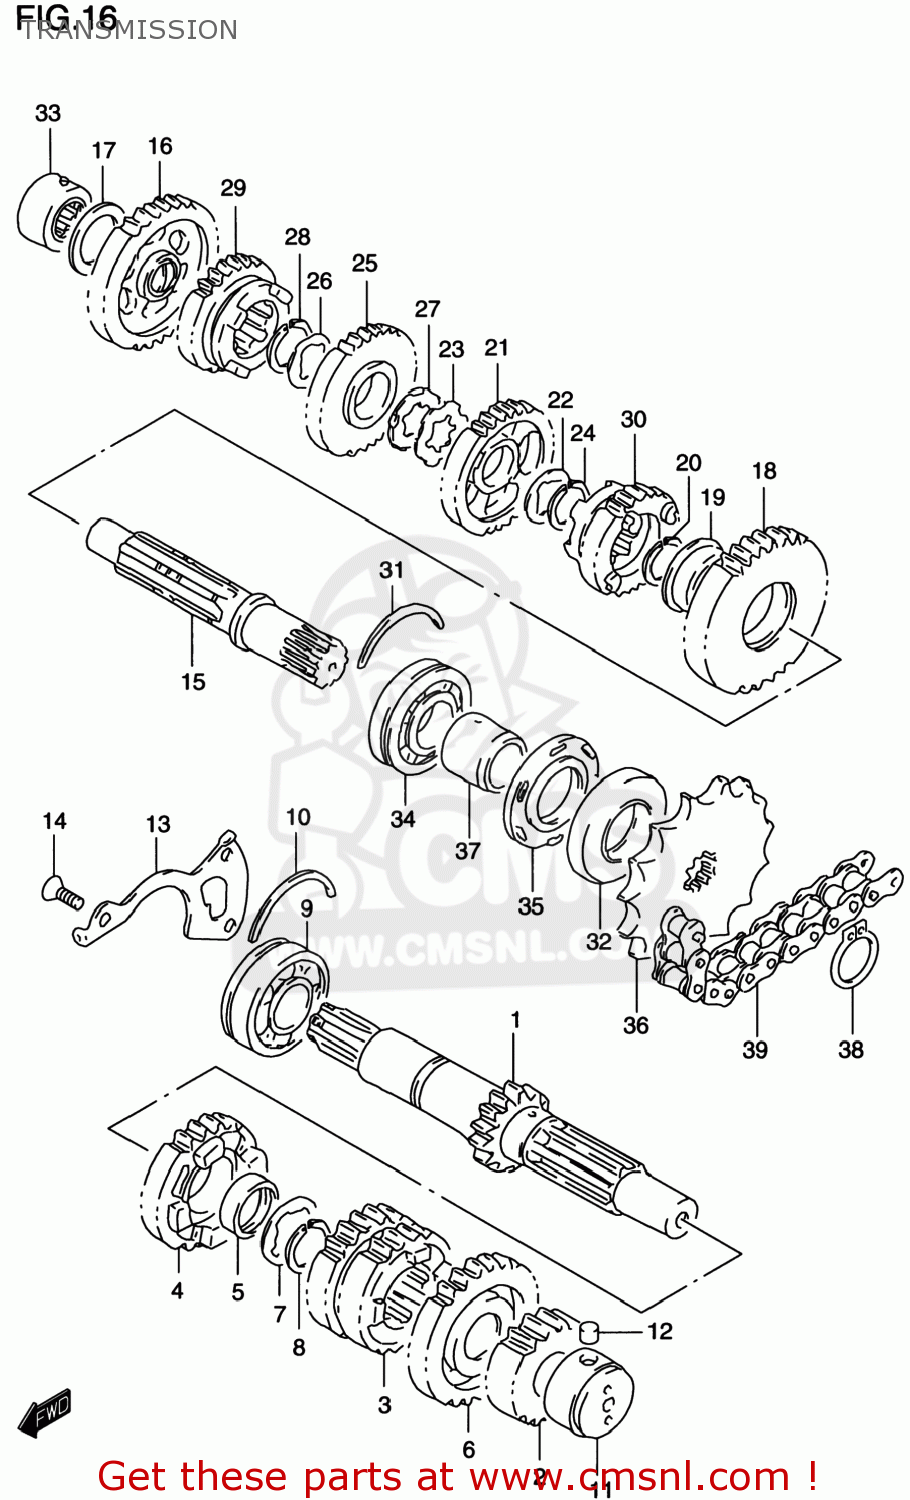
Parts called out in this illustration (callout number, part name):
1	SHAFT,COUNTER
2	GEAR,2ND DRIVE(NT:18)
3	GEAR,THIRD DRIVE
4	GEAR,FIFTH DRIVE (NT:26)
5	BUSHING 25X29X10
6	GEAR,6TH DRIVE
7	WASHER
8	CIRCLIP
9	BEARING(25X62X17)
10	C RING
11	BEARING(20X34X20)
12	PIN
13	PLATE,COUNTERSHAFT BEARING
14	SCREW ,6X16
15	SHAFT,DRIVE
16	GEAR,1ST DRIVEN
17	WASHER
18	GEAR,SECOND DRIVEN
19	BUSHING
20	CIRCLIP
21	GEAR,3RD DRIVEN
22	WASHER,LOCK
23	WASHER,LOCK
24	CIRCLIP
25	GEAR,4TH DRIVEN
26	WASHER,LOCK
27	WASHER
28	CIRCLIP
29	GEAR,5TH DRIVEN(NT:25)
30	GEAR,SIXTH DRIVEN
31	C RING
32	SEAL,OIL(32X62X7)
33	BEARING(20X34X17)
34	BEARING(25X62X17)
35	SEAL,OIL(32X62X5.5)
36	SPROCKET,ENGINE(16T)
37	SPACER,ENGINE SPROCKET
38	CIRCLIP
39	CHAIN(DID520VM,110L)
